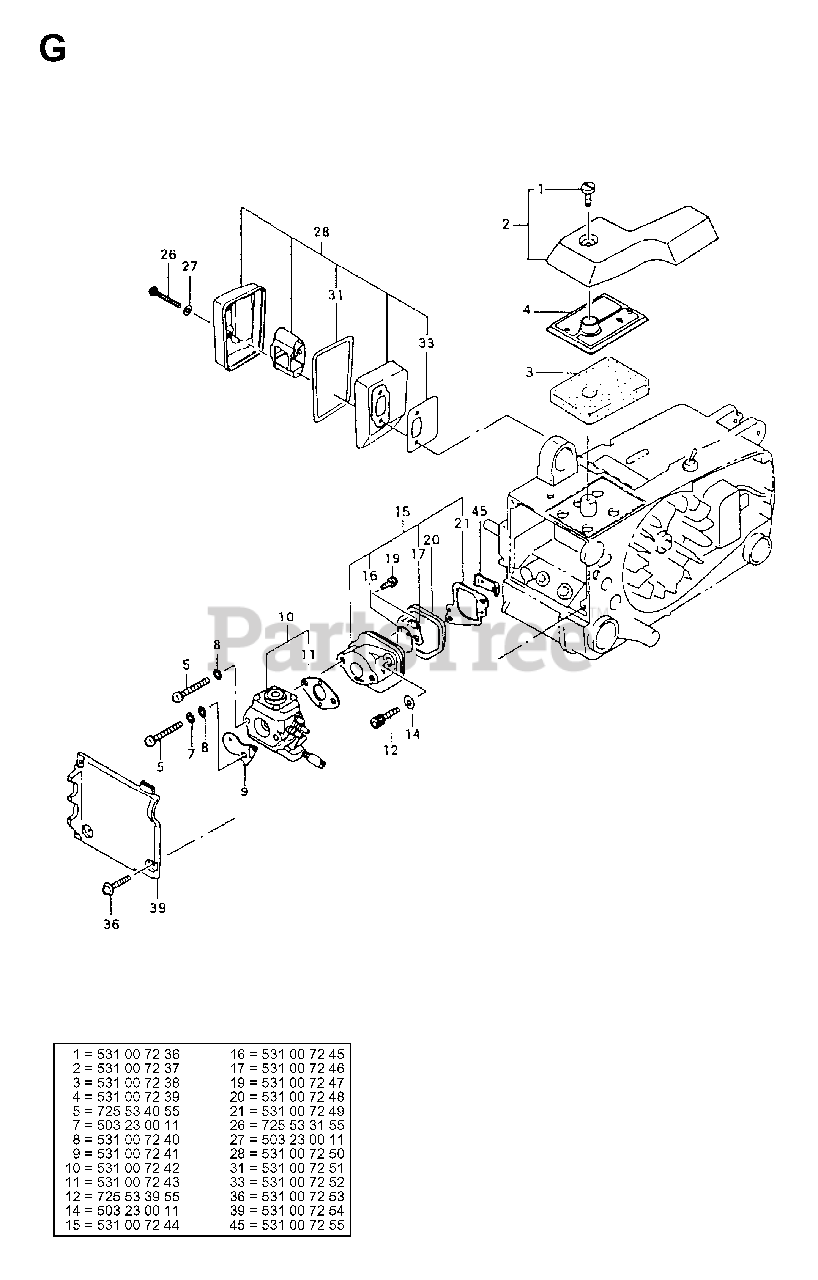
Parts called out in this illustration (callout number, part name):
5	SCREW MC6S 5X45
7	WASHER 5.3X12
9	CHOKE FLAP
10	CARBURETOR
12	SCREW MC6S 5X40
14	WASHER 5.3X12
26	SCREW MC6S 5X20
27	WASHER 5.3X12
